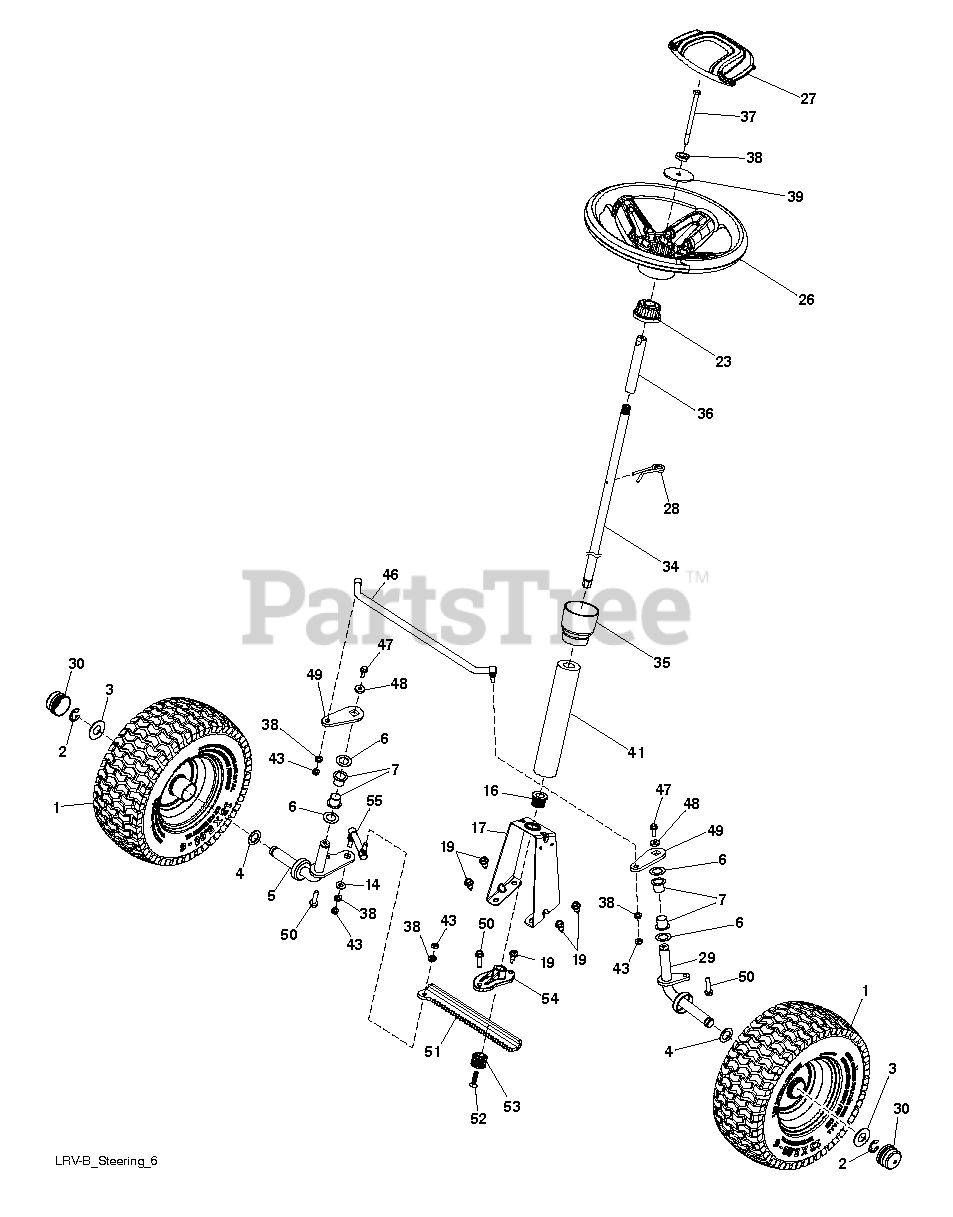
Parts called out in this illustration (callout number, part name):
1	WHEEL.TUBE.13X5.00-6.YELLOW
2	E-RING LT
3	WASHER.HARDENED
5	SPINDLE.WELDMENT.RH.E-DIP
7	Steering Column Bearing
14	WASHER M
16	Flanged Bearing, PM 5/8
17	SUPPORT.STEERING.UPPER.LRV2
19	SCREW
23	STEERING.WHEEL.ADAPTER
26	WHEEL.STEERING.MLT.BR.YEL/OVRM
27	CAP.WHL.STRNG.MULTI.BRND.YEL
28	RETAINER.CLIP.SPRING.S
29	Spindle Weldment, LH.E-Dip
30	CAP.AXLE.FRONT.YELLOW
34	Steering Shaft, Plated
35	BOOT.LOWER.STEERING.WHEEL.LRVB
36	SHAFT.EXTENSION.STEER.SPLINED
37	5/16-18X6.5.HEX.HEAD.SCREW
38	LOCKWASHER
39	WASHER.11/32
41	FOAM.SHAFT.STEERING
43	NUT, CROWNLOCK
46	Front Steering Link
47	SCREW.FLG.LOCKING.1/4-20X.75
48	WASHER LT
49	Steering Upper Arm, Pnt E-Dip
50	SCREW.THDROL.5/16-18X1.25.TYTT
51	Steering Rack Pnt
52	Screw Head Socket Lrvb
54	Steering Support Bushing
55	Drag Link, RH
